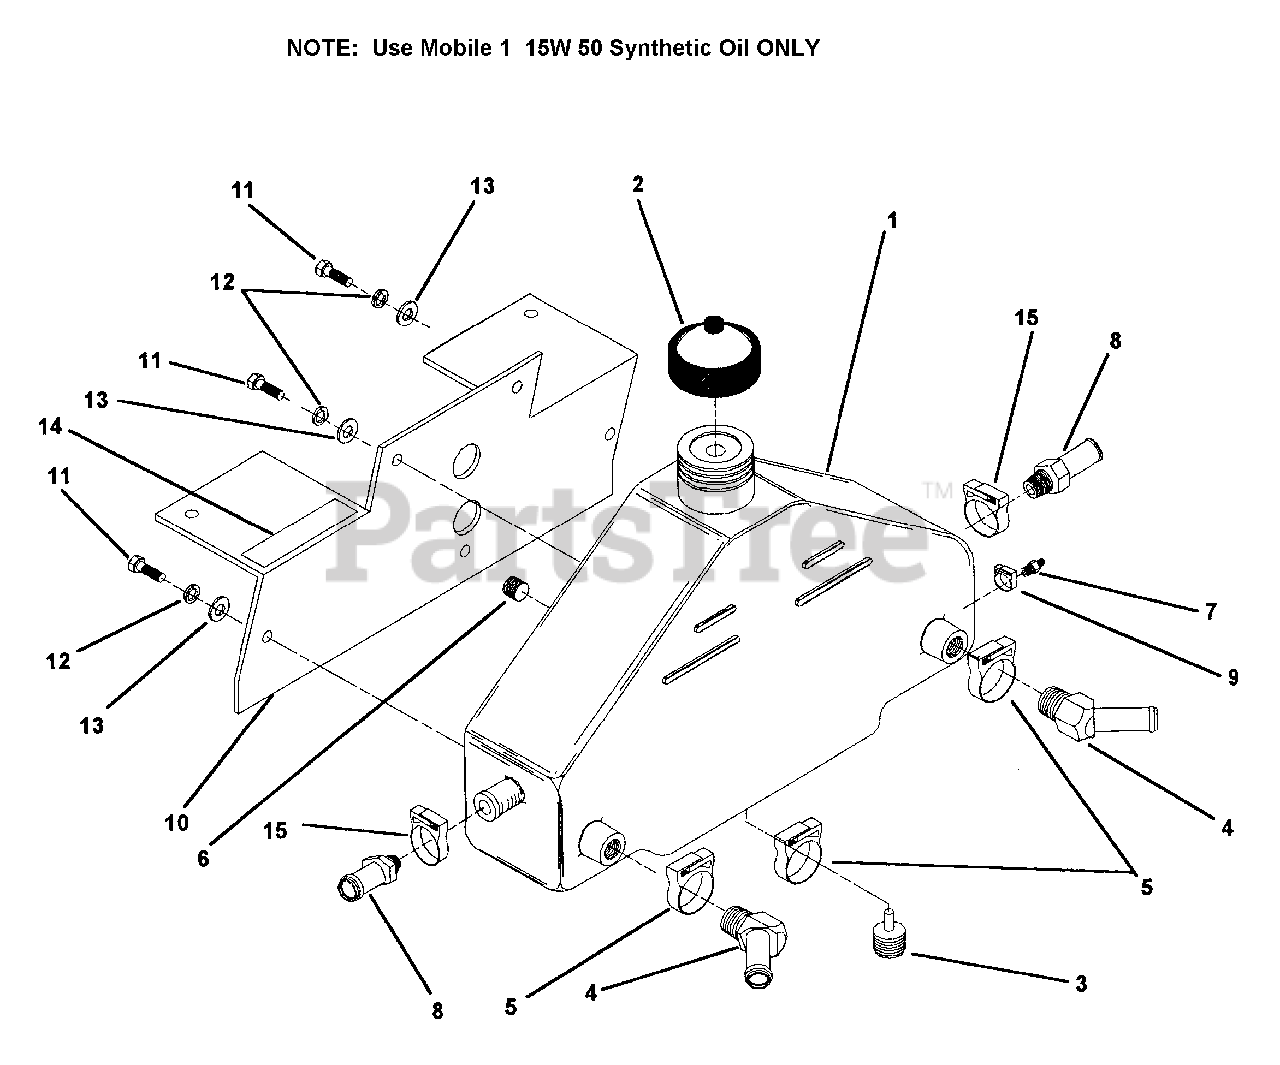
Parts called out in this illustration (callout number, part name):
1	OIL RESERVOIR UNISTAT
2	OIL CAP,
3	PLUG, MAGNETIC PIPE: 1/2"
4	ELBOW 45 DEG 1/2, NPT X 5/8
5	CLAMP,NYLON HOSE,1"
6	PIPE PLUG, 1/4 SOCKET HD
7	FITTING, 1/8 NPT X 3/8 HOSE
8	HOSE BARB, 5/8 HOSE X 1/4
9	CLAMP,NYLON HOSE 5/8"
10	MOUNTING, BRACKET
11	CAPSCREW: HH 5/16-18 X 3/4 GR. 5
12	LOCKWASHER, 5/16 HEAVY SPRING
13	WASHER, FLAT, STD, STEEL, 5/16"
14	DECAL "TRANSMISSION FLUID"
15	CLAMP,NYLON HOSE, 3/4"
